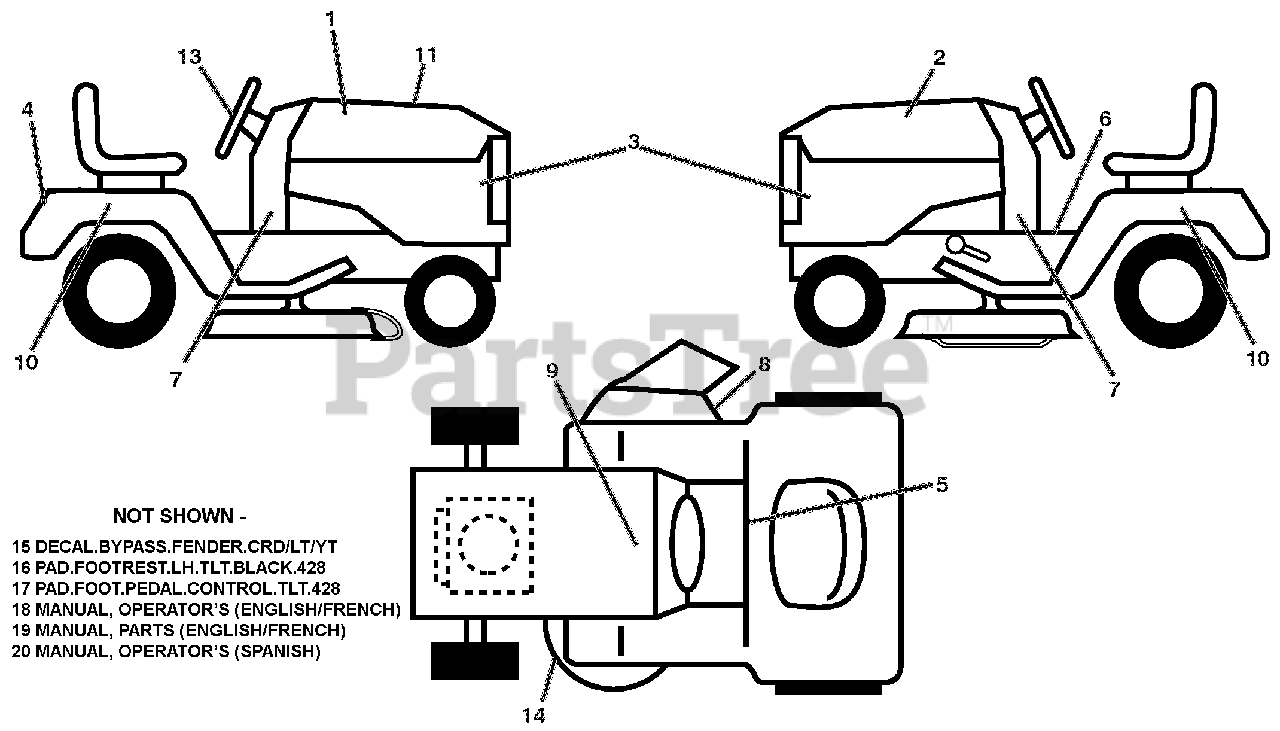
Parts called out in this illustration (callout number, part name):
1	DECAL.HOOD.RH.PRECISION.ARIENS
2	DECAL.HOOD.LH.PRECISION.ARIENS
3	DECAL.SDPNL.PWRDBY KOHL.ARIENS
4	DECAL.FENDER.REAR.ARIENS
5	Decal, Flag
6	DECAL, WARNING START INST.
7	DECAL.DASH.LWOWER.20HP.ARIENS
8	DECAL.MOWER.WARN.KEEP HAND AWY
9	DECAL.BAT.DAN/POI P/L SYM.WPN
10	DECAL.FENDER.SIDE.HYDRO.ARIENS
11	DECAL, REPLACEMENT
13	DECAL.WHEEL.STEER.ARIENS
14	DECAL.V-BELT.SCH.42/46"MEC/ELE
15	DECAL.BYPASS.FENDER.CRD/LT/YT
16	PAD.FOOTREST.LH.TLT.BLACK.428
17	PAD.FOOT.PEDAL.CONTROL.TLT.428
18	MANUAL, OPERATOR'S ENG/FRE
19	MANUAL, PARTS ENG/FRE
20	MANUAL, OPERATOR'S SPAN
